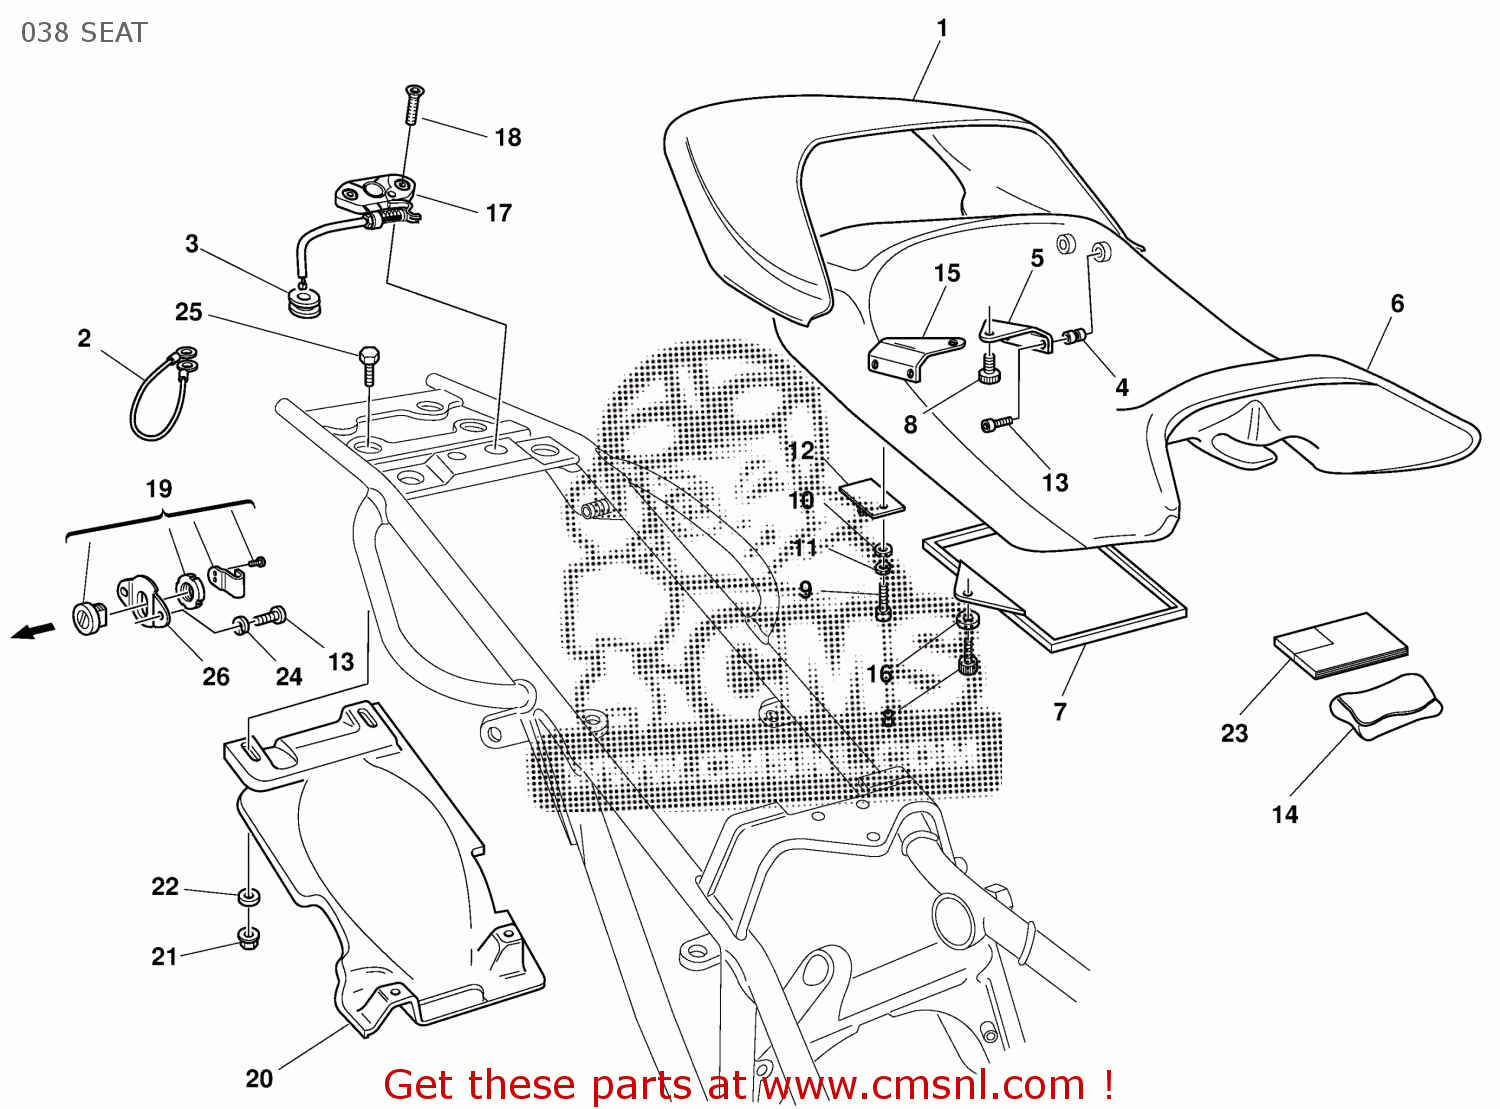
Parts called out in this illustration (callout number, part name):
1	COVER PILLION RIDER SEAT
2	ANTI-THEFT CABLE
3	RUBBER PAD
4	THREADED INSERT
5	LEFT PLATE
6	SEAT
7	CASE, TOOL, CAP
8	SCREW, SPECIAL
9	SCREW M 6X16
10	WASHER
11	WASHER, SPRING
12	PIN
13	SCREW M5X10
14	TOOL BAG
15	RIGHT PLATE
16	NYLON WASHER 15X6.2X0.5
17	CABLE, SEAT LOCK
18	SCREW M5X16
19	SEAT LOCK
20	MUDFLAP
21	NUT 6MM
22	WASHER
23	OWNERS MANUAL
24	WASHER, SPRING
25	SCREW TE M6X1.00X12
26	PLATE
